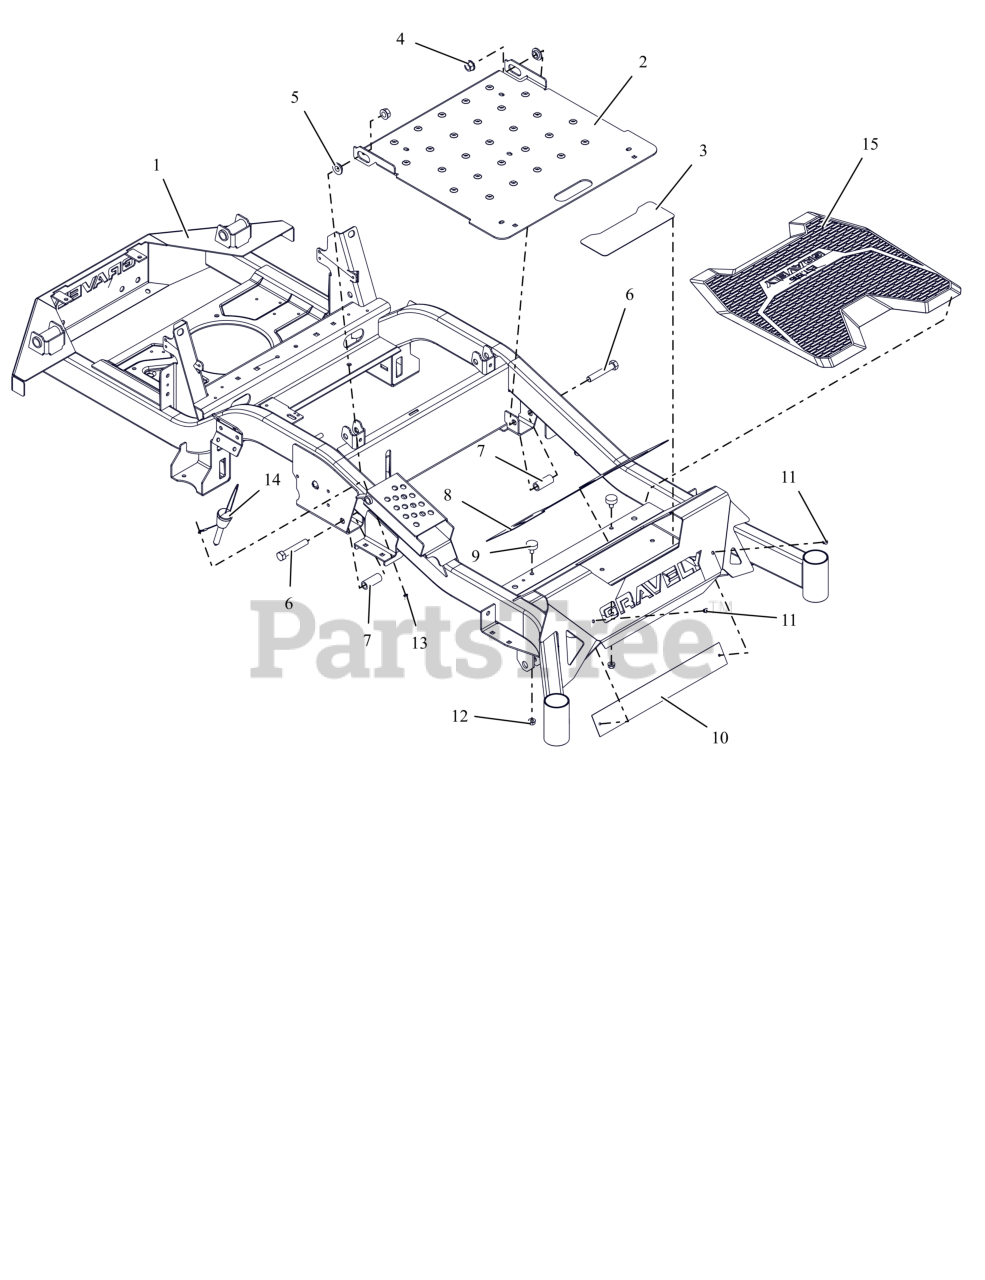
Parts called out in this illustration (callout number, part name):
1	HD 52 STEALTH FRAME W/DECALS
2	KIT,ACCESS PANEL W/DECALS-BLK
3	GRIP, STEP
4	NUT-LK-TOP-FLG .500-13 GF ZCC
5	BSHG-FLG .515X.750X.310X1.120
6	BLT, HEX .50-13X3.00 G5 ZCC
7	SPACER, .515X.75X1.83
8	GRIP, FRONT
9	BUMPER, RUBBER
10	PLATE- BACK XL FOOT-REST
11	RIVET, .1875 AL/AL .126-.250
12	NUT,SPNLK-FLG .31-18 G5 ZCC
13	POST, & SCREW, PUSH LOCK .25 X .25
14	PIN- MAGNETIC .50X2.70
15	FLOOR MAT- RUBBER HD
